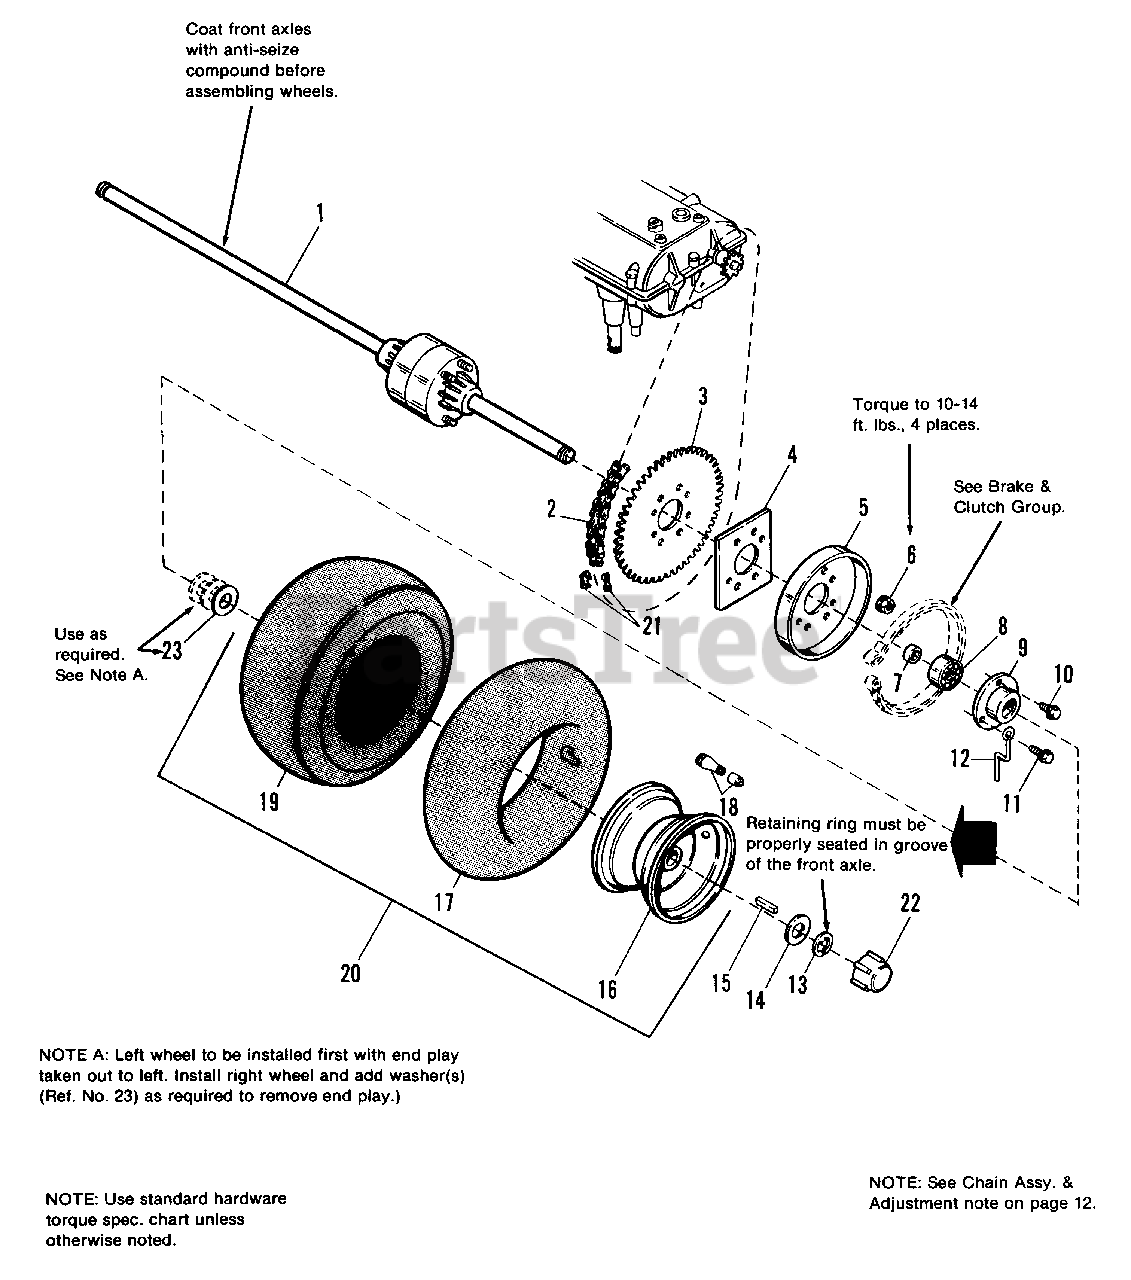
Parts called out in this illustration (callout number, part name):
1	AXLE ASSY., Differential, See page 42 for parts breakdown
2	CHAIN, Roller (#40)
3	SPROCKET, 54 Tooth
4	SHIM, Sprocket
5	DRUM, Brake
6	NUT, Whizlock, 5/16-18
7	SPACER, Axle
9	FLANGE, Bearing
10	SCREW, Taptite, 5/16-18 x 1/2
11	SCREW, Taptite, 5/16-18 x 3/4
12	STOP, Brake Band
13	RING, Retaining, Wheel
15	KEY, 3/16 x 3/16 x 1-1/2
16	WHEEL ASSY., White
16	WHEEL ASSY., Silver
17	TUBE (Service only, see note below)
18	VALVE STEM & CAP
19	TIRE, 16 x 6.50-8
20	WHEEL & TIRE ASSY., White, 16 x 6.50-8 (Incl. Ref. Nos. 16, 18, 19)
20	WHEEL & TIRE ASSY., Silver, 16 x 6.50-8 (Incl. Ref. Nos.16, 18, 19)
21	MASTER LINK, Chain #40
22	CAP, Threaded
23	WASHER, Shim, 3/4 x 1-1/16 (Use as needed)
